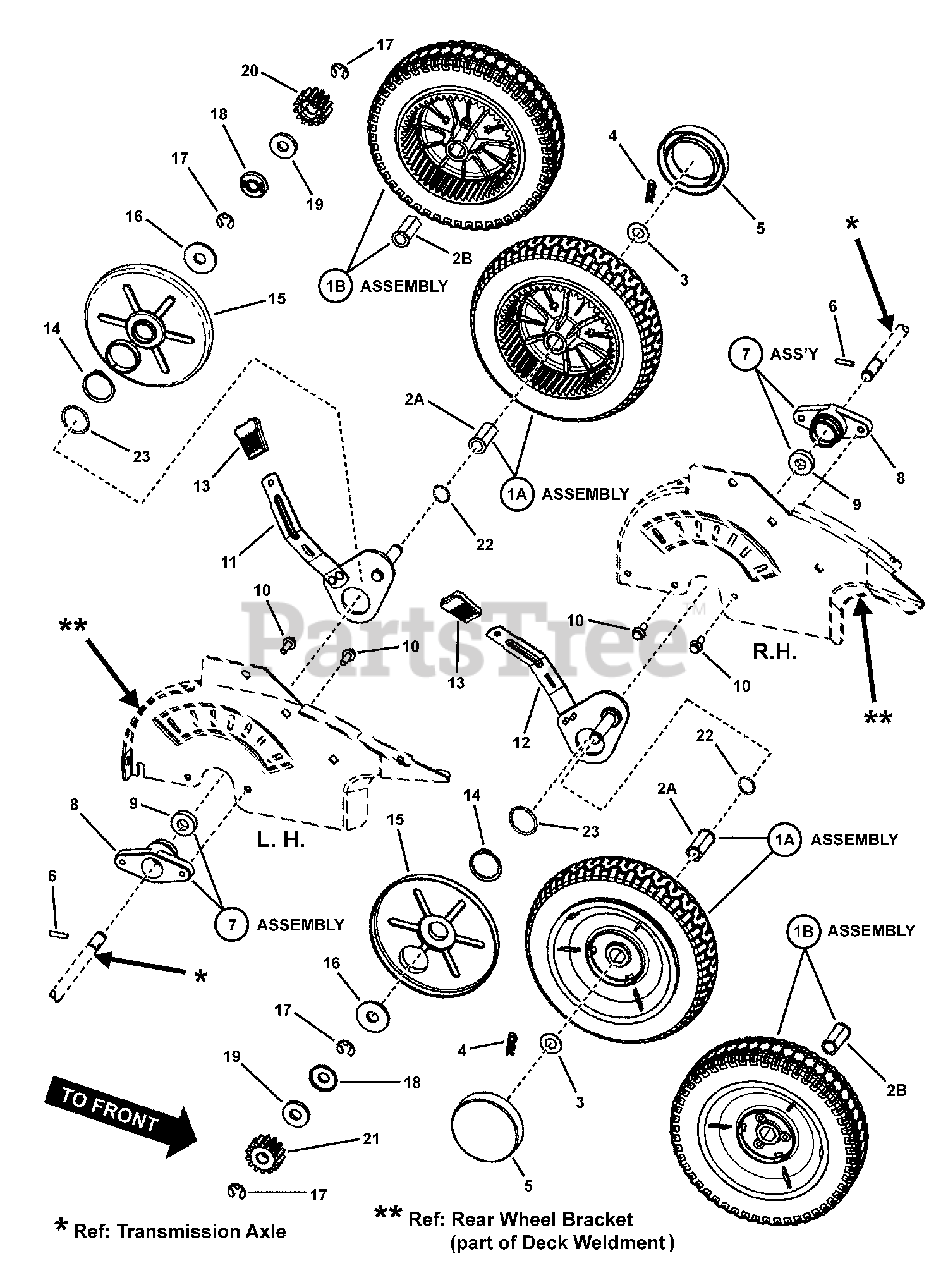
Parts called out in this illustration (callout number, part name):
1A	ASSY., 9" x 2" Gear Wheel, LS Tread & P. M. Bushing
1B	ASSY., 9" x 2" Gear Wheel, Double Bar II Tread & Nylon Bushing
2A	BUSHING, Wheel (powdered metal)
2B	BUSHING, Wheel (Nylon)
3	WASHER, 1/2" Flat
4	COTTER, Hairpin
5	HUB CAP, 3-1/4" Diameter
6	PAWL, 3/16" O.D.
7	ASSEMBLY, Axle Bearing
8	HOUSING, Axle Bearing
9	BALL BEARING, Axle
10	BOLT, 1/4-20 x 3/4" Hex Flange Lock
11	ASSEMBLY, Axle Arm, Left Rear
12	ASSEMBLY, Axle Arm, Right Rear
13	GRIP, Height Latch - Black (1.3" Wide)
14	SNAP RING, 1-3/8"
15	SHIELD, Dust
16	WASHER, .531 x 1.25 x .063
17	RETAINING RING
18	RETAINER, Pinion Seal
19	SEAL, Pinion (Felt)
20	PINION, LH Drive
21	PINION, RH Drive
22	O-RING, Buna N, 018
23	O-RING, Buna N, 124
